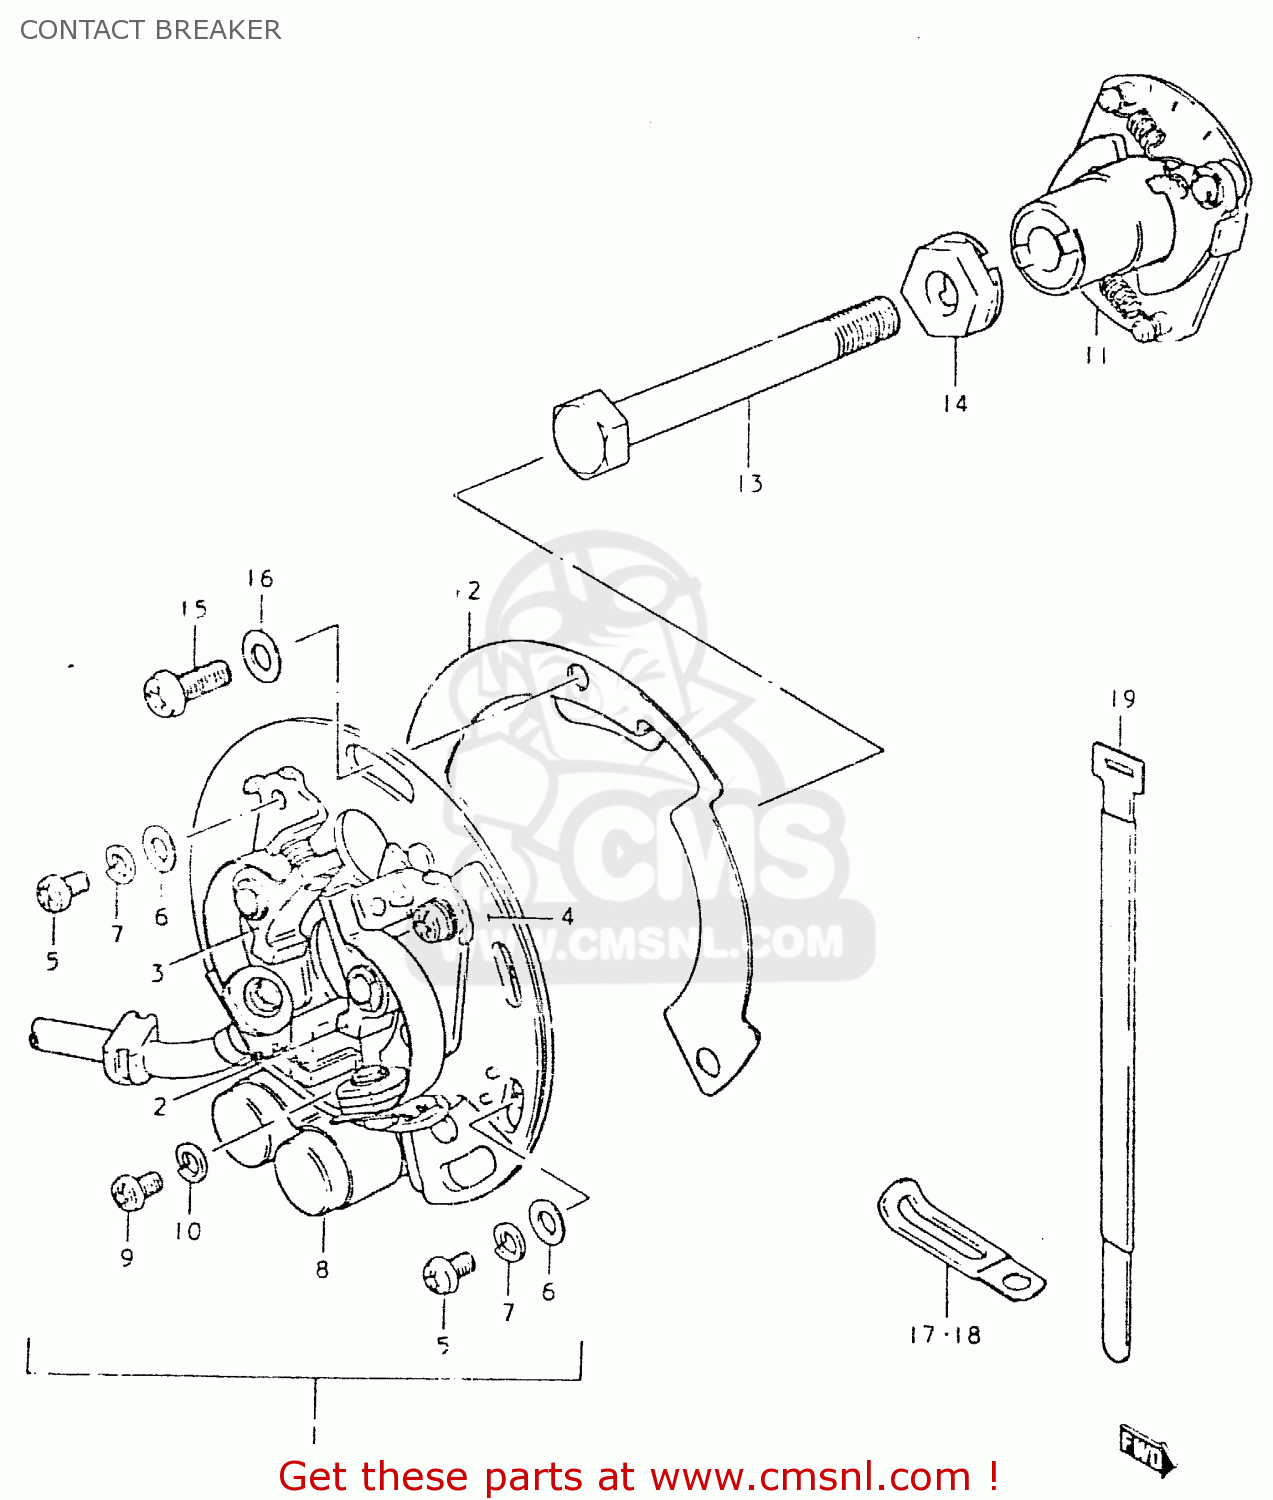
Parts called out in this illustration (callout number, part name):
1	BREAKER ASSEMBLY,CONTACT
2	POINT ASSEMBLY,CONTACT
3	POINT ASSEMBLY,CONTACT
4	PLATE,CONTACT POINT
5	SCREW 4X6
6	WASHER
7	LOCK WASHER
8	CONDENSER
9	SCREW 4X6
10	LOCK WASHER
11	GOVERNOR ASSEMBLY
12	PLATE,IGNITION TIMING
13	BOLT
14	WASHER
15	SCREW(5X12)
16	WASHER
17	CLAMP L:35
18	CLAMP
19	CLAMP
